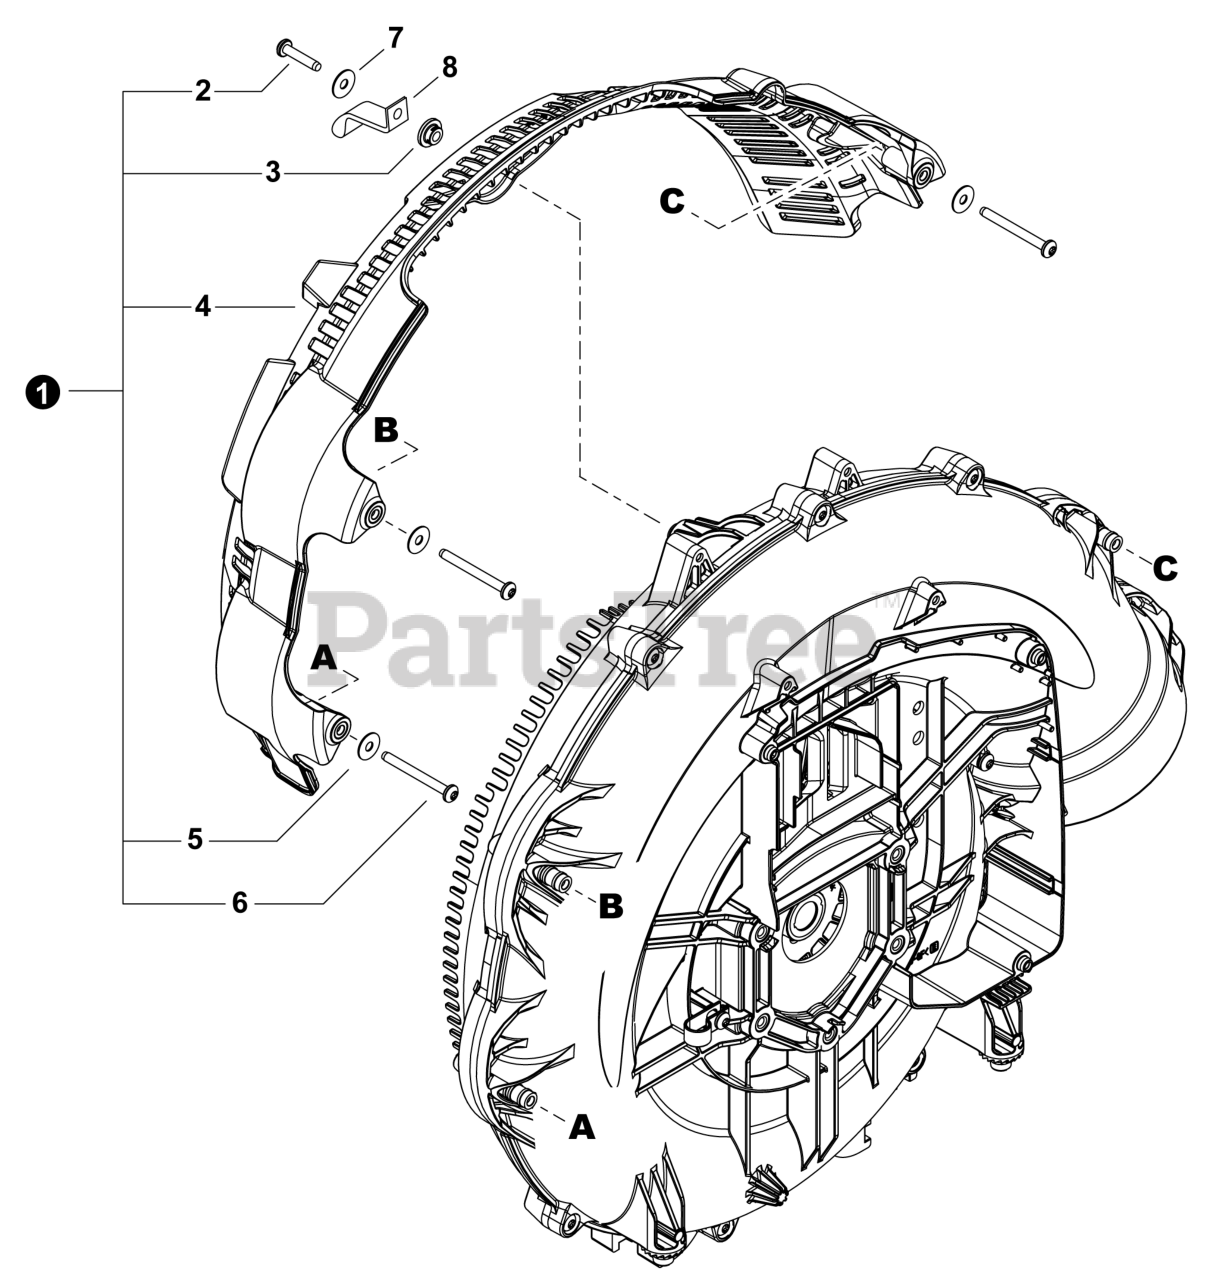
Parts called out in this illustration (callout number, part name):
1	GUARD KIT, LEAF
2	BOLT, TORX 5x25
3	COLLAR 5
4	GUARD, LEAF
5	WASHER 5.5x16x0.8
6	BOLT, TORX 5x50
7	WASHER 5.5x16x0.8
8	STRAP, SAFETY
